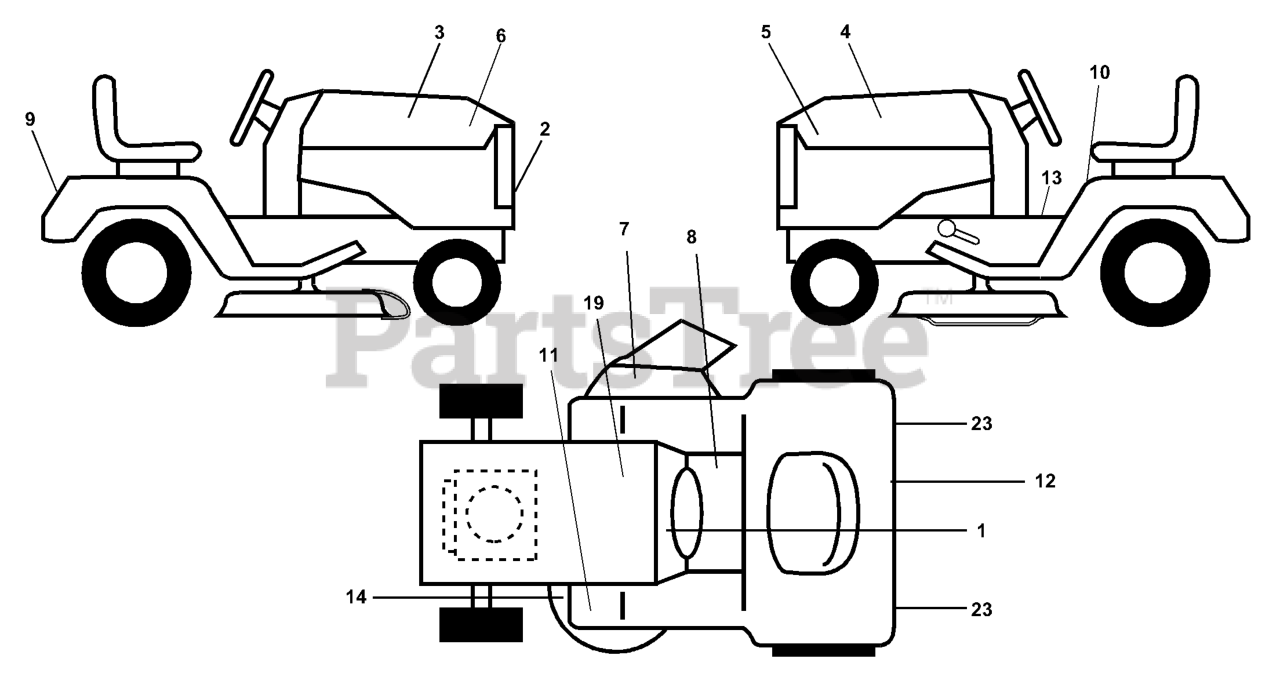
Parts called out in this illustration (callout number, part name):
2	DECAL GRILL HUSQ NLA
3	DECAL-HOOD R.H.
4	DECAL-HOOD L.H.
5	DECAL HOOD LH
6	DECAL HOOD RH
7	DECAL WARNING (ENGLISH/FRENCH)
8	DECAL PARK BRAKE
9	DECAL FENDER NLA
10	DECAL CAUTION
12	DECAL D-BAR
23	REFLECTOR-TAIL YT
